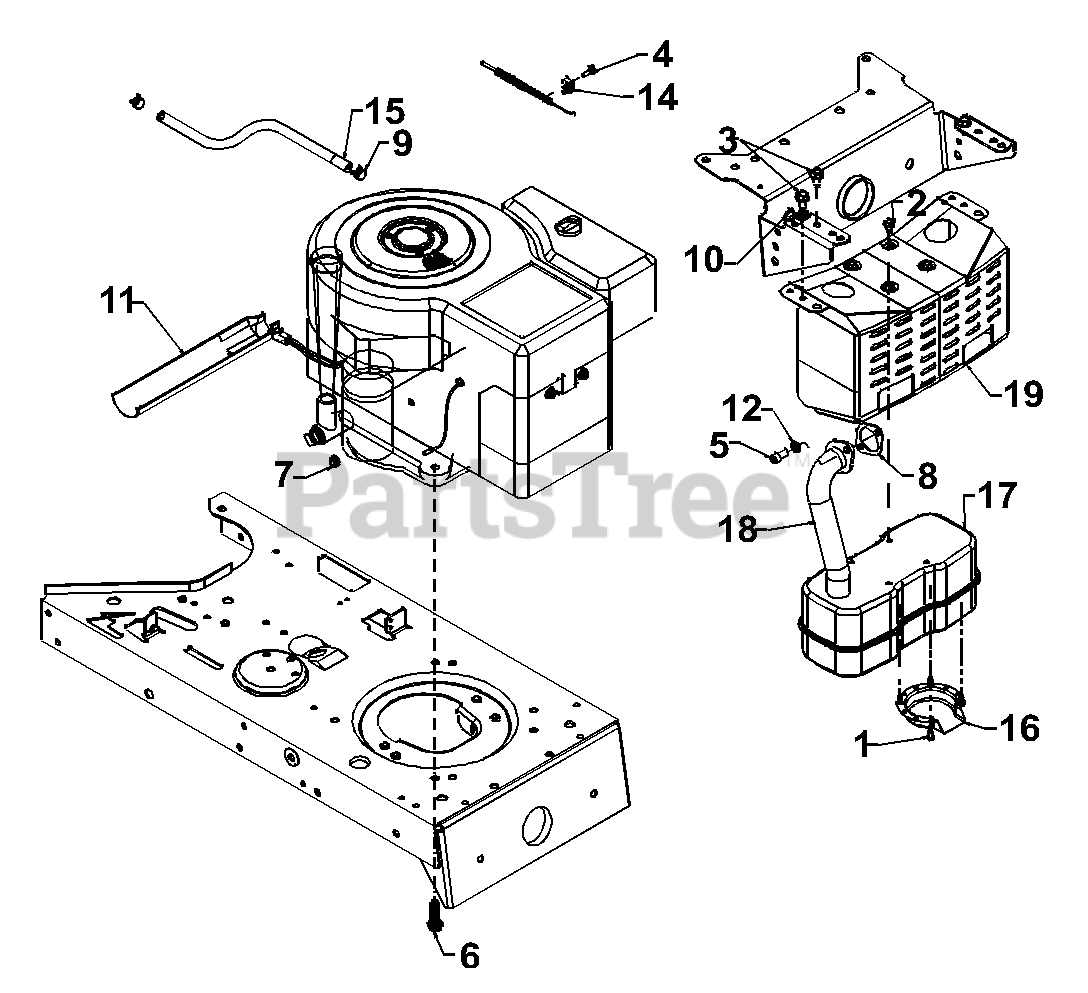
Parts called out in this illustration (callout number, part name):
1	Hex Slot Scr. #8-32 x .38" Lg.
2	Hex Wash. TT-Tap Scr. 1/4-20 x .5" Lg.
3	Hex Wash Hd. TT-Tap Scr. 5/ 16-18 x .62" Lg.
4	Scr. #10-32:.620 Hx. Slot Wash.
5	Socket Hd. Bolt 5/16-18 x .62" Lg.
6	Scr. 3/8-16 x 1.25
7	Nut, Hex 1/4-20
8	Exhaust Gasket
9	Hose Clamp .49 Dia.
10	Clamp 9/16 Dia.
11	Oil Drain Sleeve
12	L-Wash. 5/16" I.D.
14	Casing Clamp, Throttle, B&S
15	Fuel Line Hose
16	Muffler Deflector
17	Muffler
18	Exhaust Pipe
